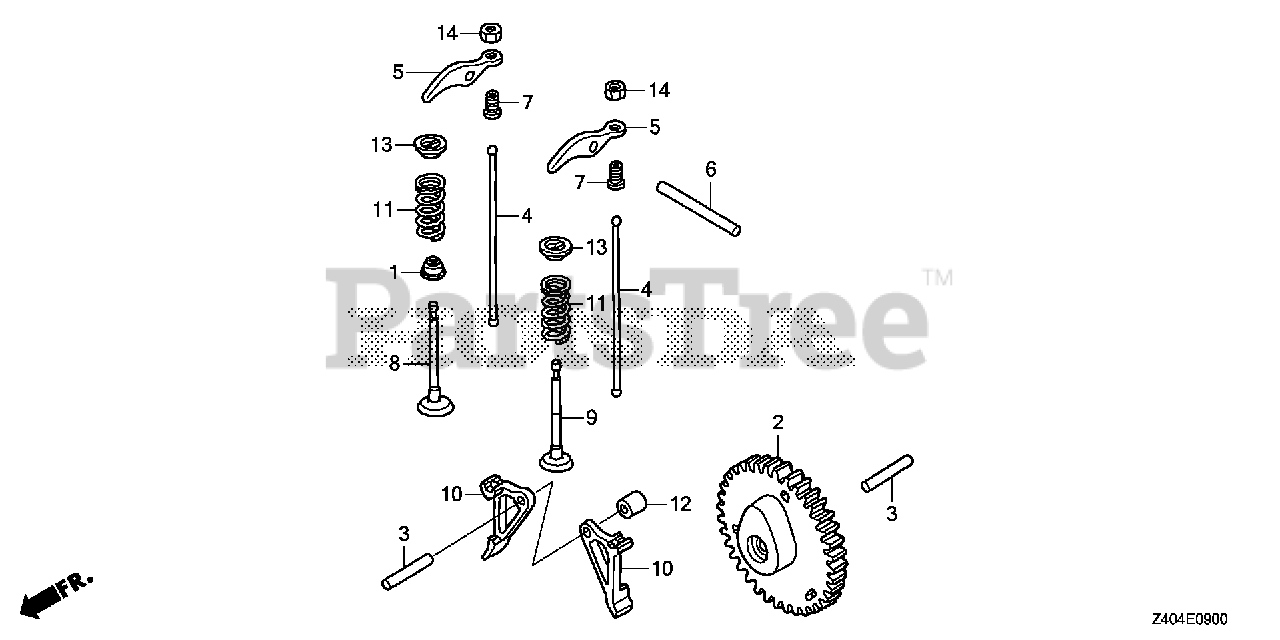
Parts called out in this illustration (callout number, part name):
1	SEAL, VALVE STEM
2	CAMSHAFT ASSY.
3	ROLLER (5X29.8)
5	ARM, VALVE ROCKER
6	ROLLER (4X37.8)
7	PIVOT, ROCKER ARM
8	VALVE, IN.
9	VALVE, EX.
10	LIFTER, VALVE
11	SPRING, VALVE
12	COLLAR, LIFTER
13	RETAINER, VALVE SPRING
14	NUT, TAPPET ADJUSTING
